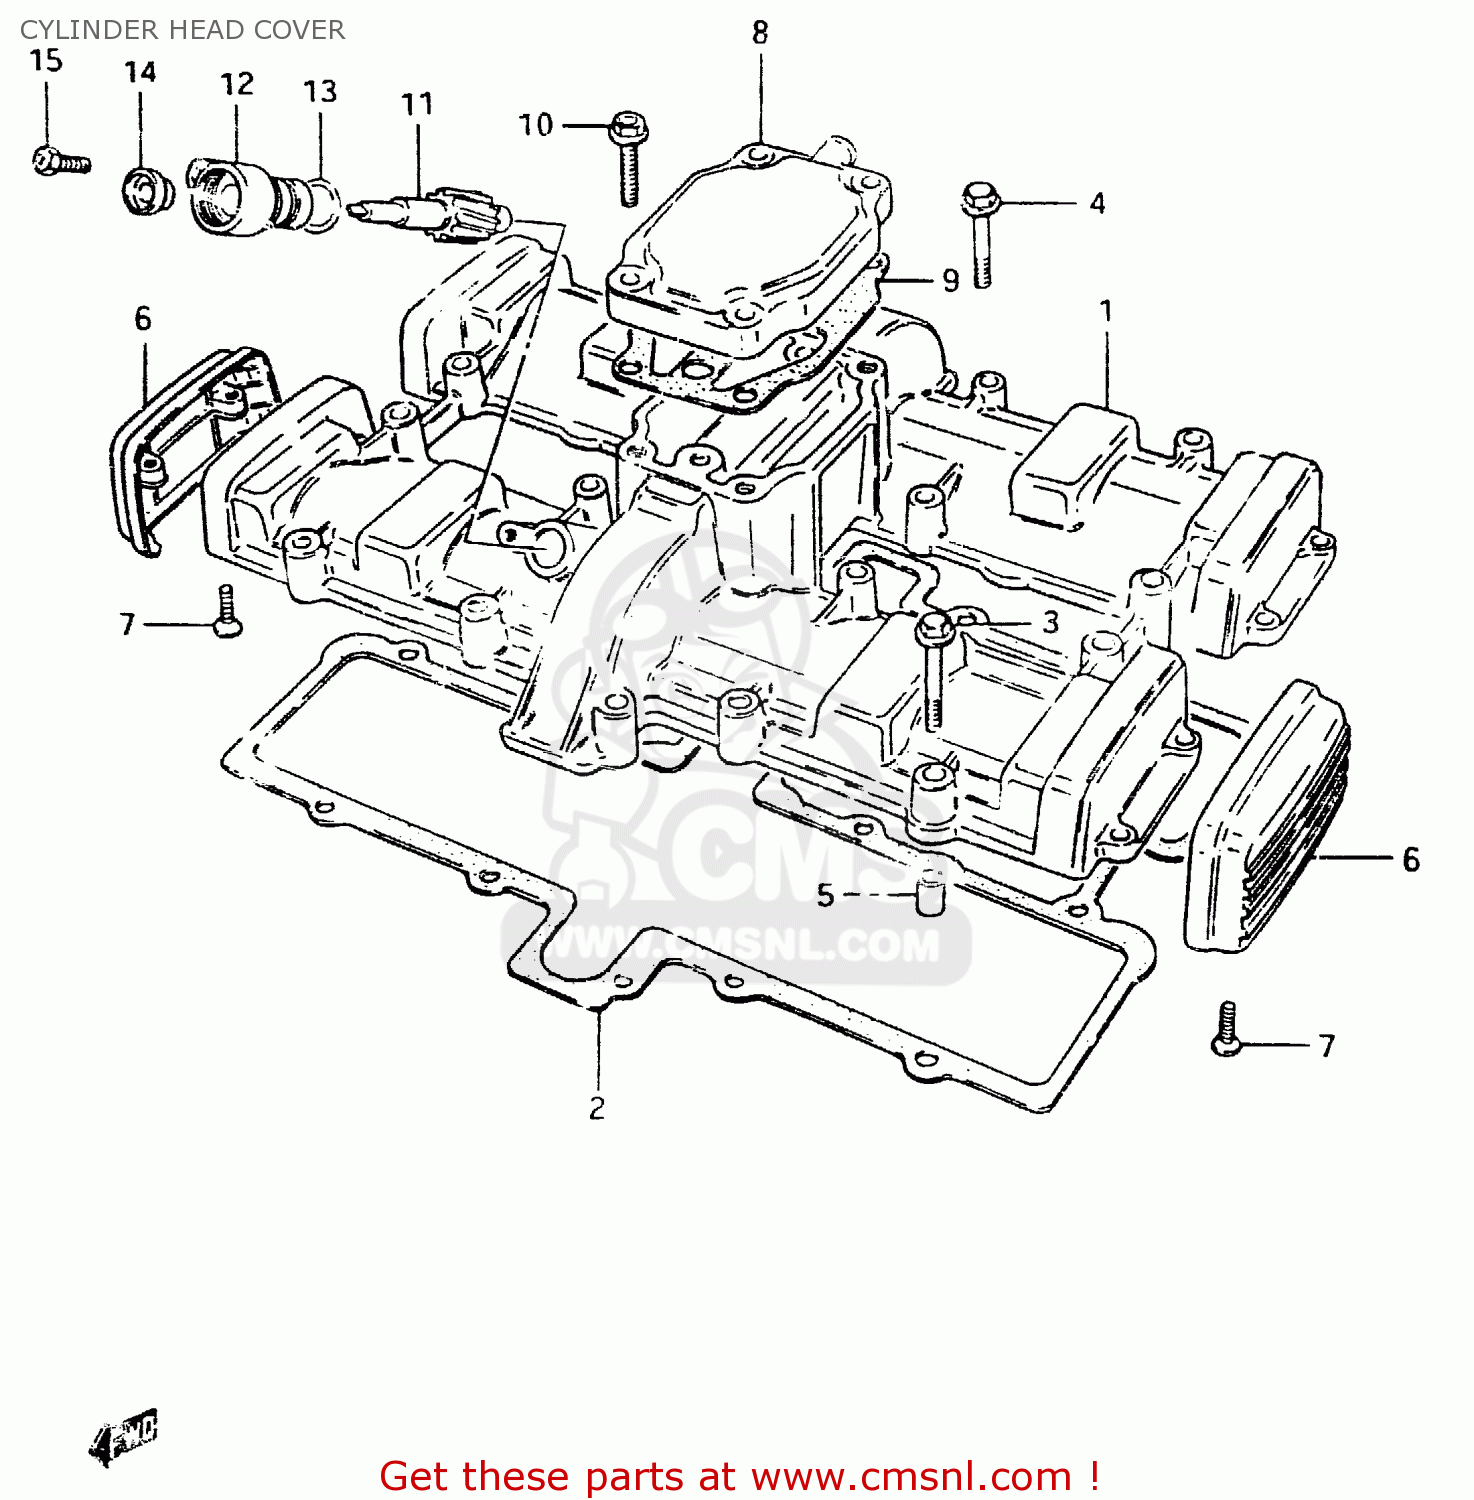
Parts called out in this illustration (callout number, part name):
1	COVER, CYLINDER HEAD
2	GASKET (MCA)
3	BOLT (6X40)
4	BOLT
5	PIN(6.2X8X11)
6	CAP, CYLINDER HEAD COVER
7	SCREW
8	COVER, BREATHER
9	GASKET (MCA)
10	BOLT
11	GEAR,TACHOMETER DRIVEN
12	SLEEVE,TACHOMETER DRIVE GEAR
13	SEAL,TACHOMETER DRIVEN
14	SEAL,OIL(5X12X8)
15	SCREW(5X12)
